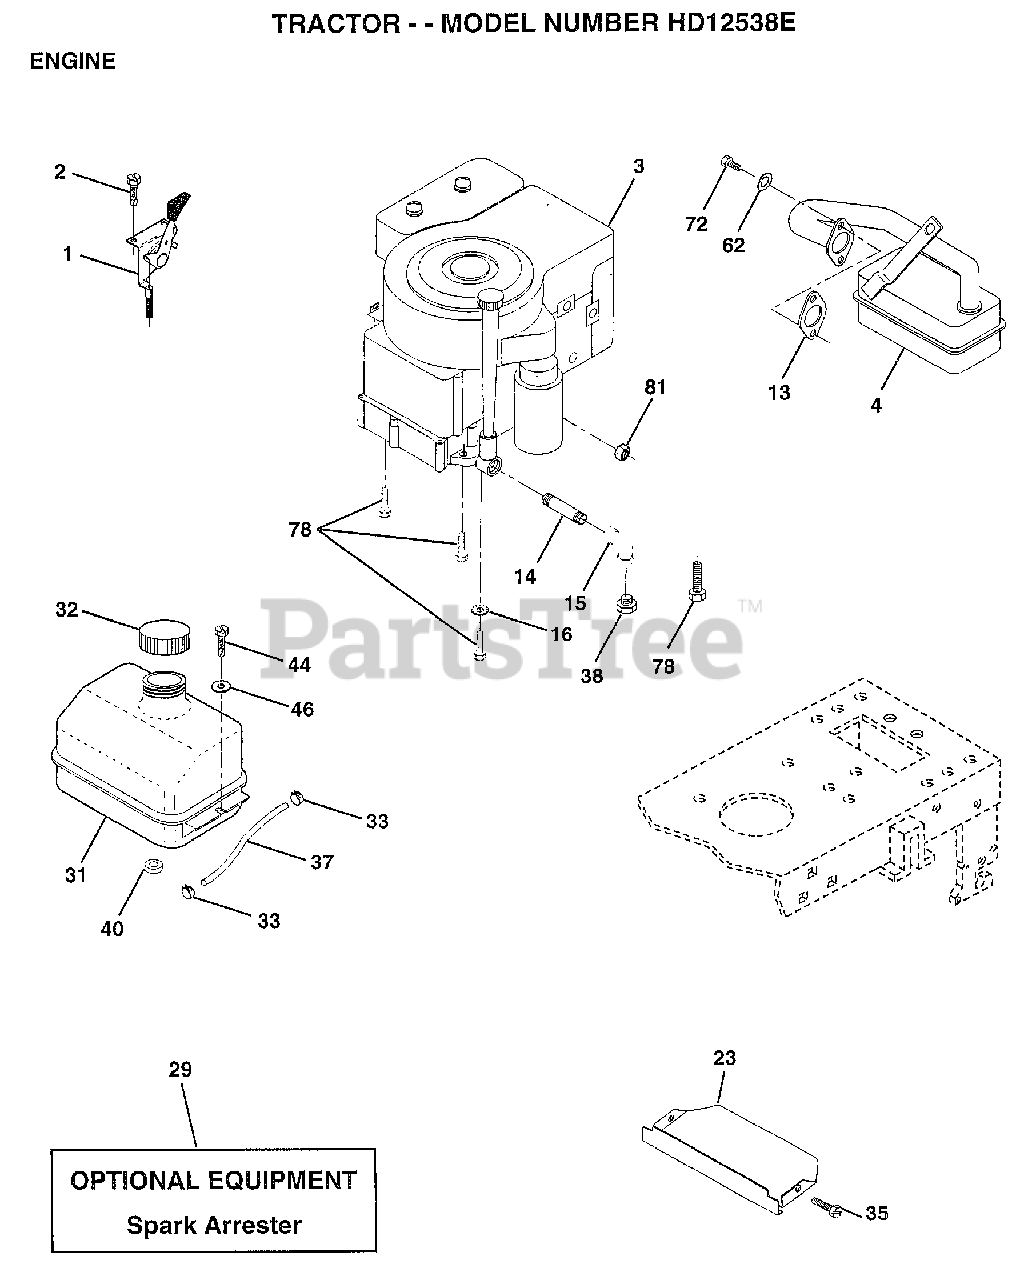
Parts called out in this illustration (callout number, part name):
1	CONTROL THROTTLE
2	SCREW LT
4	MUFFLER
13	GASKET ENG 1 313 LD TIN PLATED
14	PIPE NIPPLE
15	ELBOW
16	LOCKWASHER
23	SHIELD.BRN/DBR.GD
31	TANK.FUEL.LT.
32	CAP ASM FUEL
33	HOSE CLAMP
35	SCREW
37	LINE FUEL
44	SCREW HEX CRT
46	WASHER
62	LOCKWASHER
72	SCREW
78	SCREW
81	NUT
